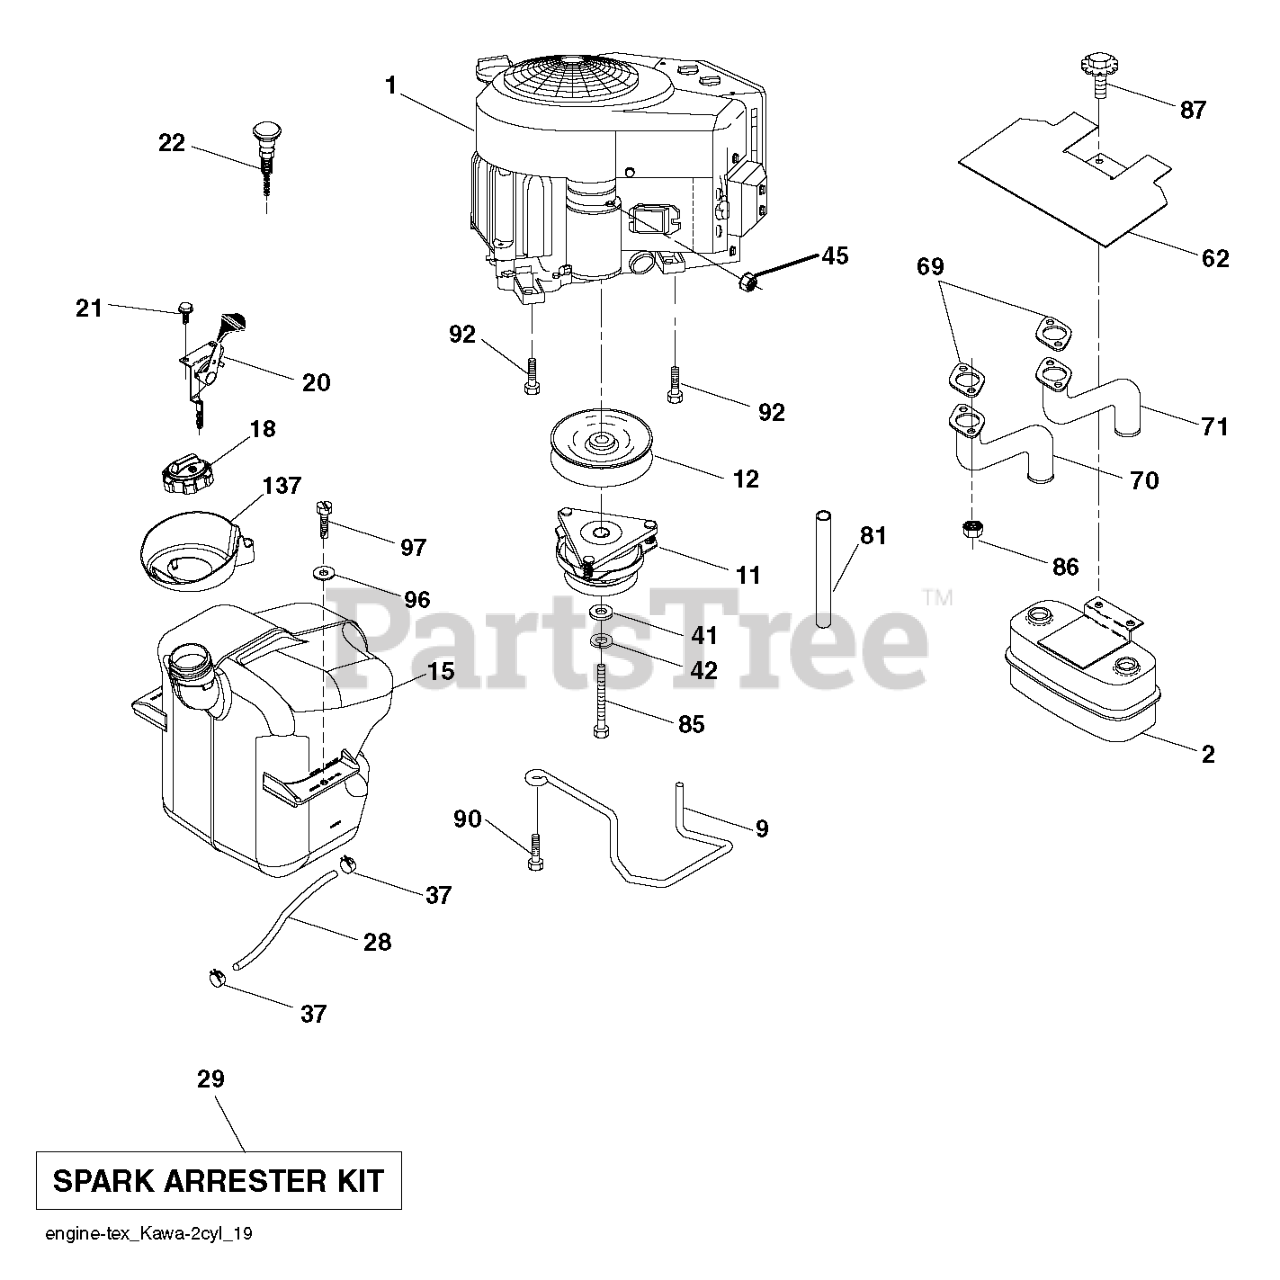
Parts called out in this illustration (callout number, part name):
2	MUFFLER.ASM.TWN.EXTNDED.DFLCTR
9	KEEPER.BELT.ENGINE.4.2
11	CLUTCH.ELECTRIC.LT.48"*
12	PULLEY.ENGINE.TUFFTORQ
15	FUEL TANK TANK. ASSEMBLY. EXTE
18	CAP.ASM.FUEL.2.25"TOP.TURN
20	CONTROL.THROTTLE.COBRA.BLACK
21	SCREW.#10 X 0.750.BOS
22	CONTROL, CHOKE
28	LINE.FUEL.20
29	KIT.SPARK ARRESTOR 794945 B&S
37	HOSE CLAMP
42	LOCKWASHER
45	NUT
62	SHIELD.HEAT.MUFFLER
70	TUBE.EXHAUST.LH.FR961/FR730
71	TUBE.EXHAUST.RH.FR961/FR730
81	TUBE, DRAIN OIL ASM.
85	BOLT HEX 7/16-20X4-1/4"
86	NUT.HEX.FLANGE.TOPLOCK
87	BOLT 5/1618UNC X 3/4 W/ SEMS
90	SCREW 3/8-16X1
92	SCREW 3/8-16X1
96	WASHER
97	SCREW HEXWSHR 1/4-20X3/4
